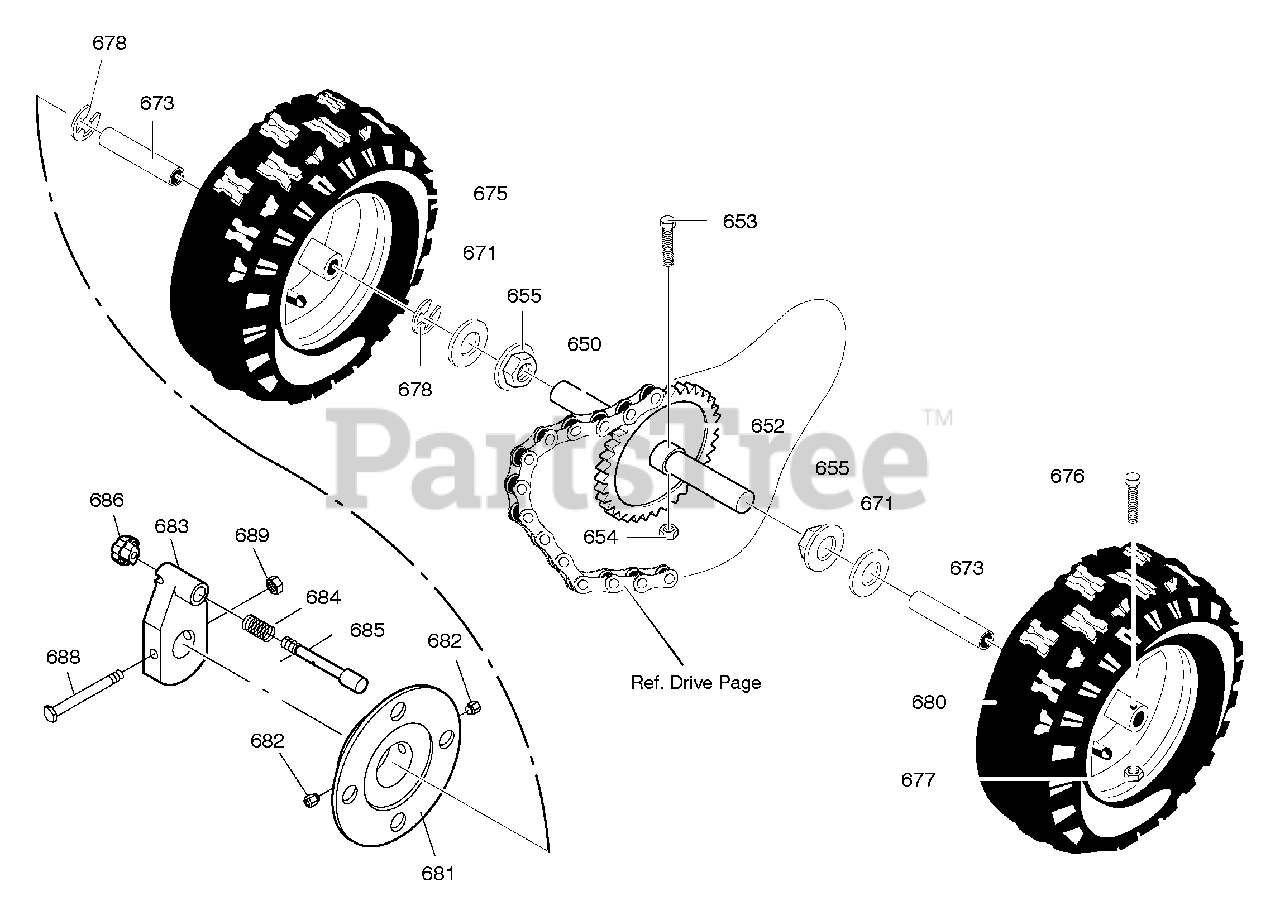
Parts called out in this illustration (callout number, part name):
650	SHAFT, AXLE
652	SPRKT & HUB
653	SCREW, 1/4-20X1.75
654	NUT, 1/4-20 HEX NYLOCK
655	BEARING, AXLE
671	FLATWASHER
673	BUSHING, WHEEL
675	TIRE & RIM, RIGHT
676	SCREW, 1/4-20X1.75
677	NUT, 1/4-20 HEX NYLOCK
678	RING, RET
680	TIRE & RIM, LEFT
681	DISC, WHEEL
682	SCREW
683	HUB ASSEMBLY, WHEEL LOCK
684	SPRING, COMPRESSION *
685	PIN, LOCK *
686	KNOB *
688	SCREW
689	NUT
